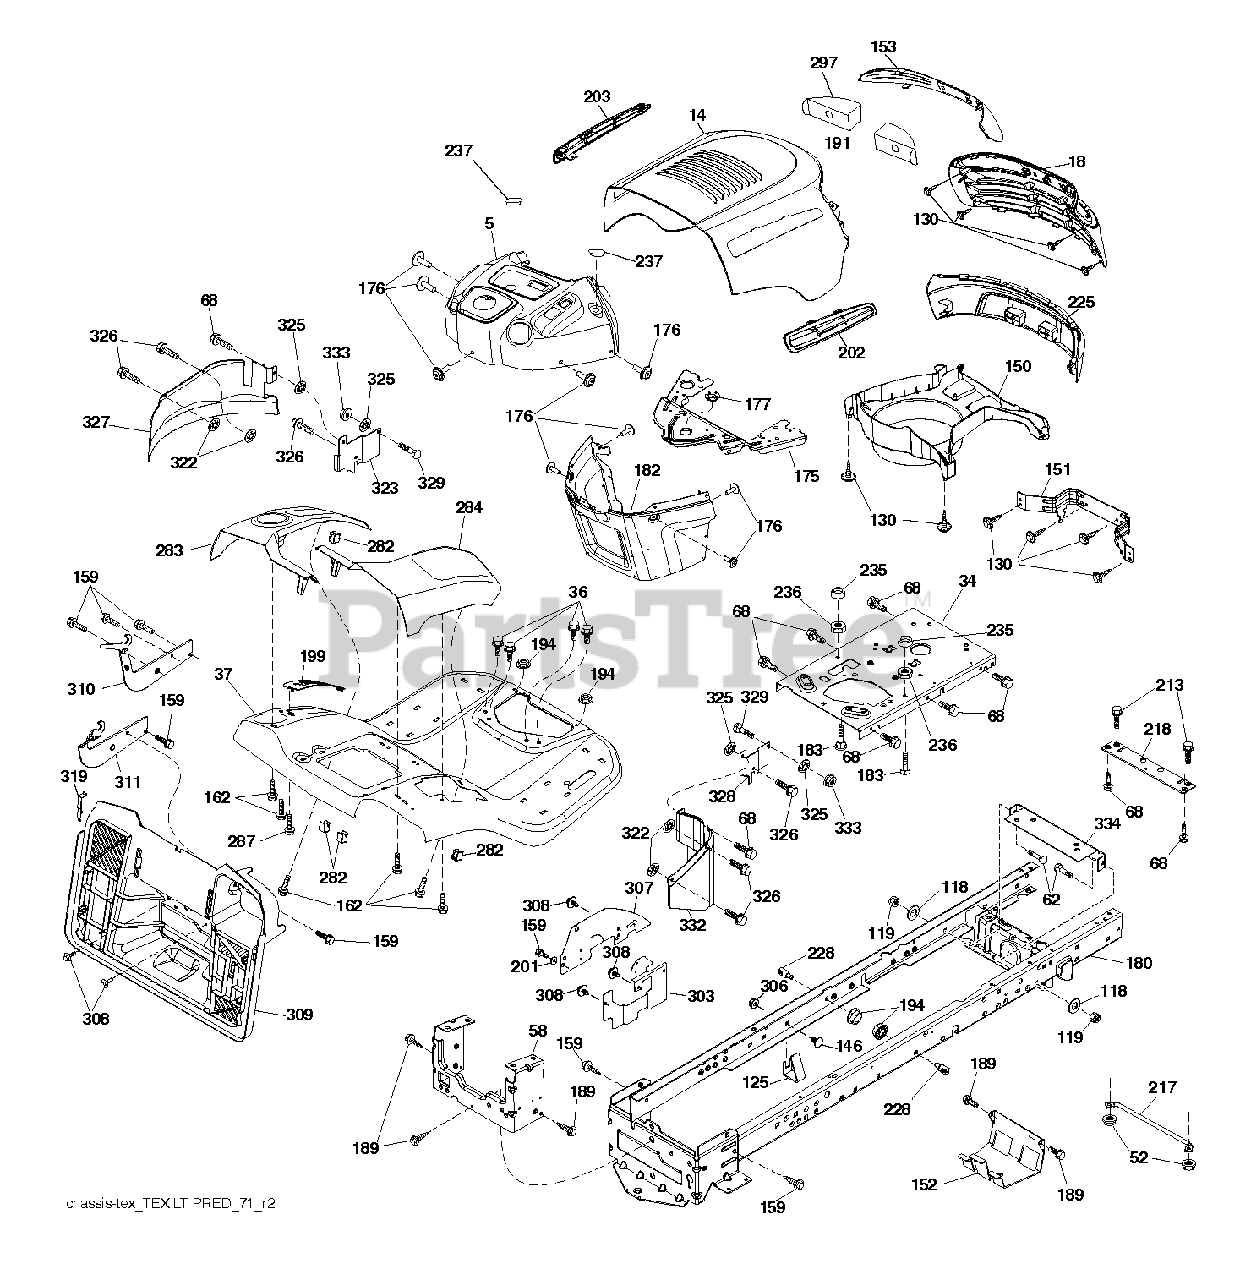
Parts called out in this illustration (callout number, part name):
36	SCREW 5/16"
52	LOCKNUT
58	DRAWBAR UPPER 2PC SMALL FENDER
119	LOCKNUT
125	Fuel Line Clip
130	SCREW.#10 X 0.750.BOS THREAD
146	BOLT.RDHD.SHT.SQNK.3
151	BRACKET.PIVOT.ALPHA.LT
152	SHIELD BROWNING
153	LENS.PREDATOR.LT
159	SCREW, 3/8-16X3/4
162	SCREW.HI-LO.CONSOLE
175	CROSSMEMBER
176	SCREW.#10-24X5/8.RN.QU
177	BUSHING STEERING
182	DASH.LWER.PREDATOR/HUSQ.LT
183	BOLT.5/16-18X1-1/4 FULL THD
189	SCREW
191	INSERT.REFLECT.PREDATOR.LT.RH
194	NUT LOCK HEX FLANGE 5/16-18
201	WASHER
213	BOLT
217	ROD.PIVOT.HOOD
218	X-PIECE.HOOD.STOP.NON/
228	STUD.FASTNER.W/ANTI-ROTATE
235	SPACER FENDER
236	NUT.CENTERLOCK.5/16-
237	PLUG.MOUNT.CARGO.BLK
282	CLIP.RETAINER.CONSOLE.LT.HUSQ
297	REFLECTOR.INSERT.PRED.LH.LT
306	NUT LOCK FLG 3/8-16 UNC
308	BOLT, 5/16-18 X 1 3/4
310	BRACKET BRACKET.LH RE
311	BRACKET BRACKET.RH RE
322	PALNUT 1/4
326	SCREW 14-20 X 5/8
329	BOLT
333	NUT.71038.31-18.HEX.NYLOCK
